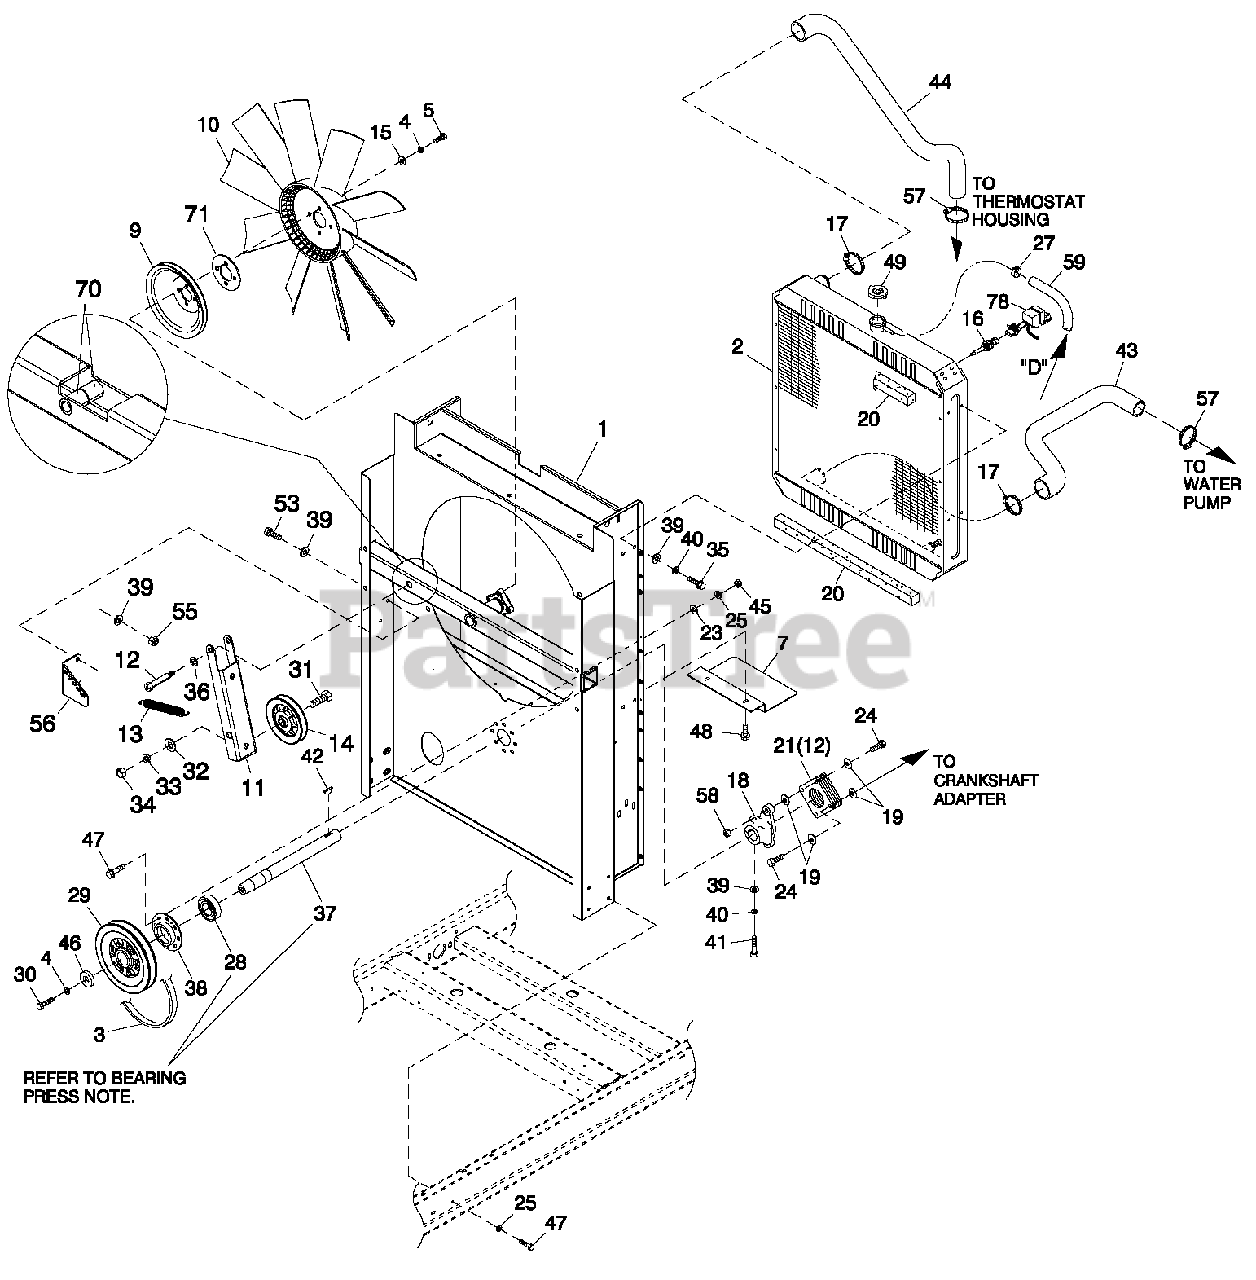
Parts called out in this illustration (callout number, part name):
1	WELDMENT RADIATOR SUPPORT C2
2	RADIATOR 598 X 568 X 49 CPL RH
3	V-BELT 31/64" X 57-3/8"
4	WASHER LOCK M10
5	SCREW HHC M 10-1.5X 30 G10.9
9	PULLEY FAN V-GROOVE 9"
10	FAN COOL 22" D IA 10 BLADE LH
11	ARM BELTTENSIONER
12	SHOULDER BOLT 1/2 X 2-1/4"
14	PULLEY V-BELT 4" FLANGED
15	WASHER FLAT 3/8-M10 ZINC
17	CLAMP HOSE #28 1.32-2.25
18	HUB FLEX PLATE
20	TAPE FOAM 1 X 1 (26.75" LG)
21	DISK FLEX
23	WASHER FLAT 1/4-M6 ZINC
24	SCREW HHC 5/16-24X 1.124
25	WASHER LOCK M6-1/4
27	CLAMP HOSE BAND 1/4
28	BEARING #6205 2NSE C3 E SRI2 S
29	PULLEY 5.125" DIA MACHINED
30	SCREW HHC M 10-1.5X 30 G8.8
31	SCREW HHC 1/2-13 X 2" G8
32	WASHER FLAT 1/2 ZINC
33	WASHER LOCK 1/2
34	NUT HEX 1/2-13 STEEL
35	SCREW HHFC M8-1.25 X 20 W/M6
36	WASHER NYLON .50 X .87 X .06
37	SHAFT FAN DRIVE
38	RETAINER BEARING
39	WASHER FLAT 5/16-M8 ZINC
40	WASHER LOCK M8-5/16
42	KEY WOODRUFF 4 X 19D
43	HOSE LOWER RADIATOR G2
44	HOSE UPPER RADIATOR G2 (USED WITH MANFLD P/N 0G0707)
45	NUT HEX M 6 X 1.0 G 8Y E L CHR
46	SPACER .5 X 1.5 X .25 STL/ZINC
47	SCREW HHFC M 6 -1 .0X 2 0 G8.8
48	SCREW THF M6-1 X 16 N W A Z/JS
49	CAP RADIATOR 13 PSI
53	SCREW HHC M 8 -1 .25 X 20 C 8 .8
55	NUT HEX LOCK M8-1.25 NY INS
56	BRACKET TENSIONER SPRING
57	CLAMP HOSE #24 B1.06-2.00
58	NUT HEX LOCK 5/16-24 NY INS
59	HOSE 9/32 ID (36" LG)
70	BEARING SLEEVE 1/2 /X 3 /4 X 1
